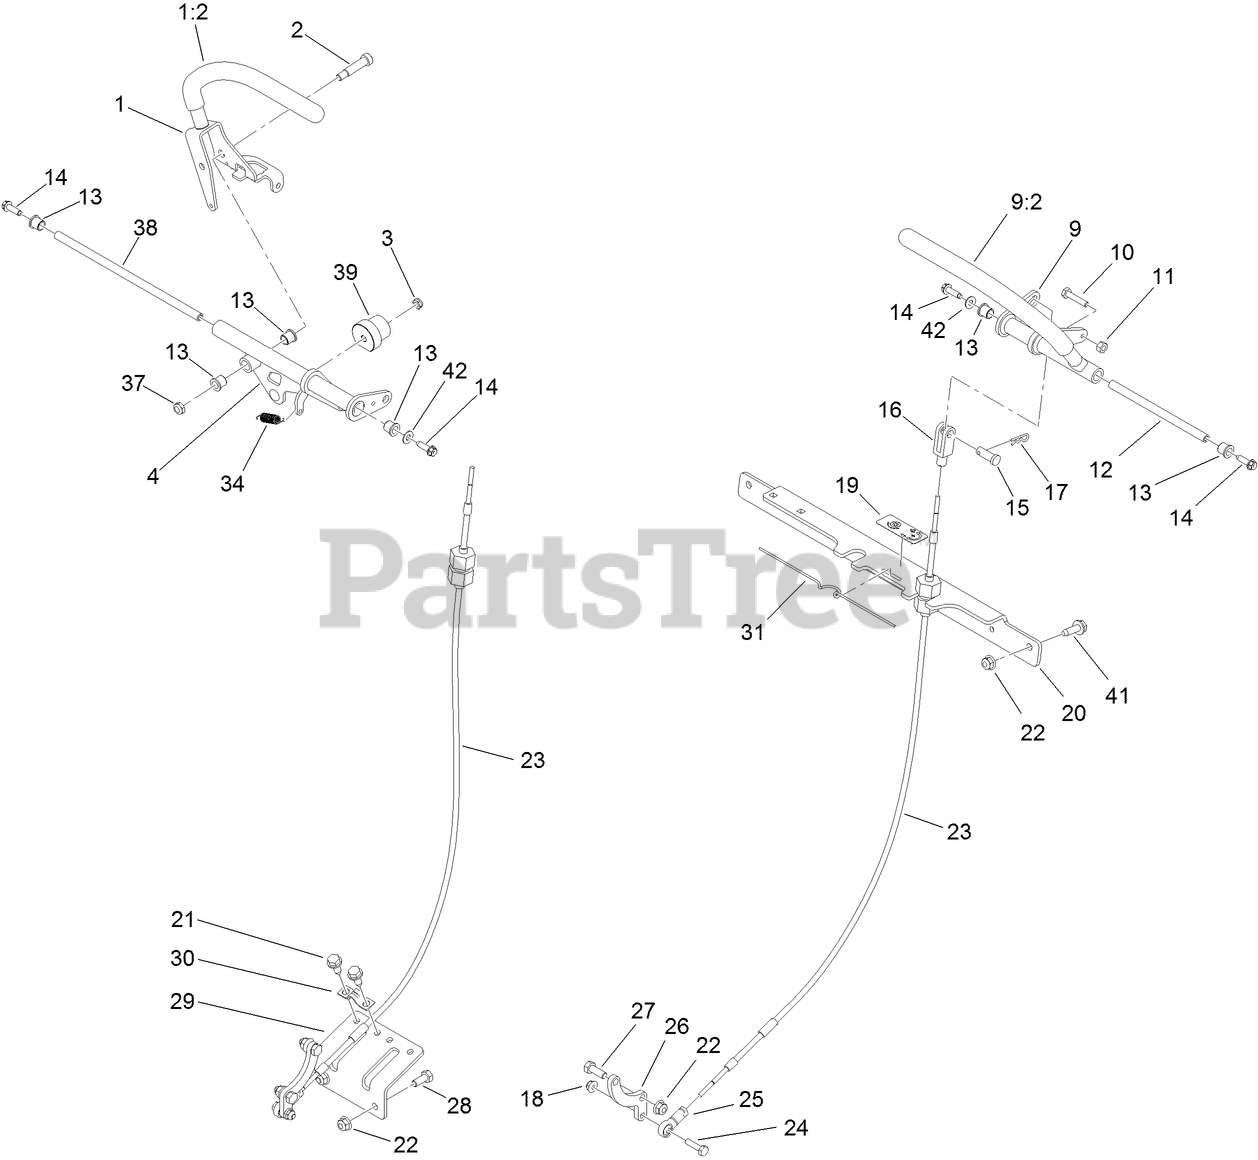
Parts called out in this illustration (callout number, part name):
1	RH LEVER ASM
2	SCREW-HSH
3	NUT-LOCK, NI
4	RH MOTION CONTROL ASM
9	LH MOTION CONTROL ASM
10	SCREW-HH
11	NUT-HEX
12	SHAFT-PIVOT, MOTION CONTROL
13	BEARING
14	SCREW-HH, TORX
15	PIN-CLEVIS
16	YOKE-FEMALE
17	PIN-COTTER
18	NUT-HF
19	DECAL-TRACKING, HYDRO
20	BRACKET-CROSS
21	SCREW-HWHTF
22	NUT-HF, NI
23	CABLE ASM
24	SCREW-HH
25	ROD END-BALL JOINT
26	ARM-CONTROL, PUMP
27	SCREW-HH
28	BOLT-CARR
29	BRACKET-CLAMP, CABLE
30	CLAMP-CABLE
31	CLIP-SPRING
34	SPRING-EXTENSION
37	NUT-LOCK, NI
38	SHAFT-PIVOT
41	SCREW-HHF
42	WASHER-FLAT
